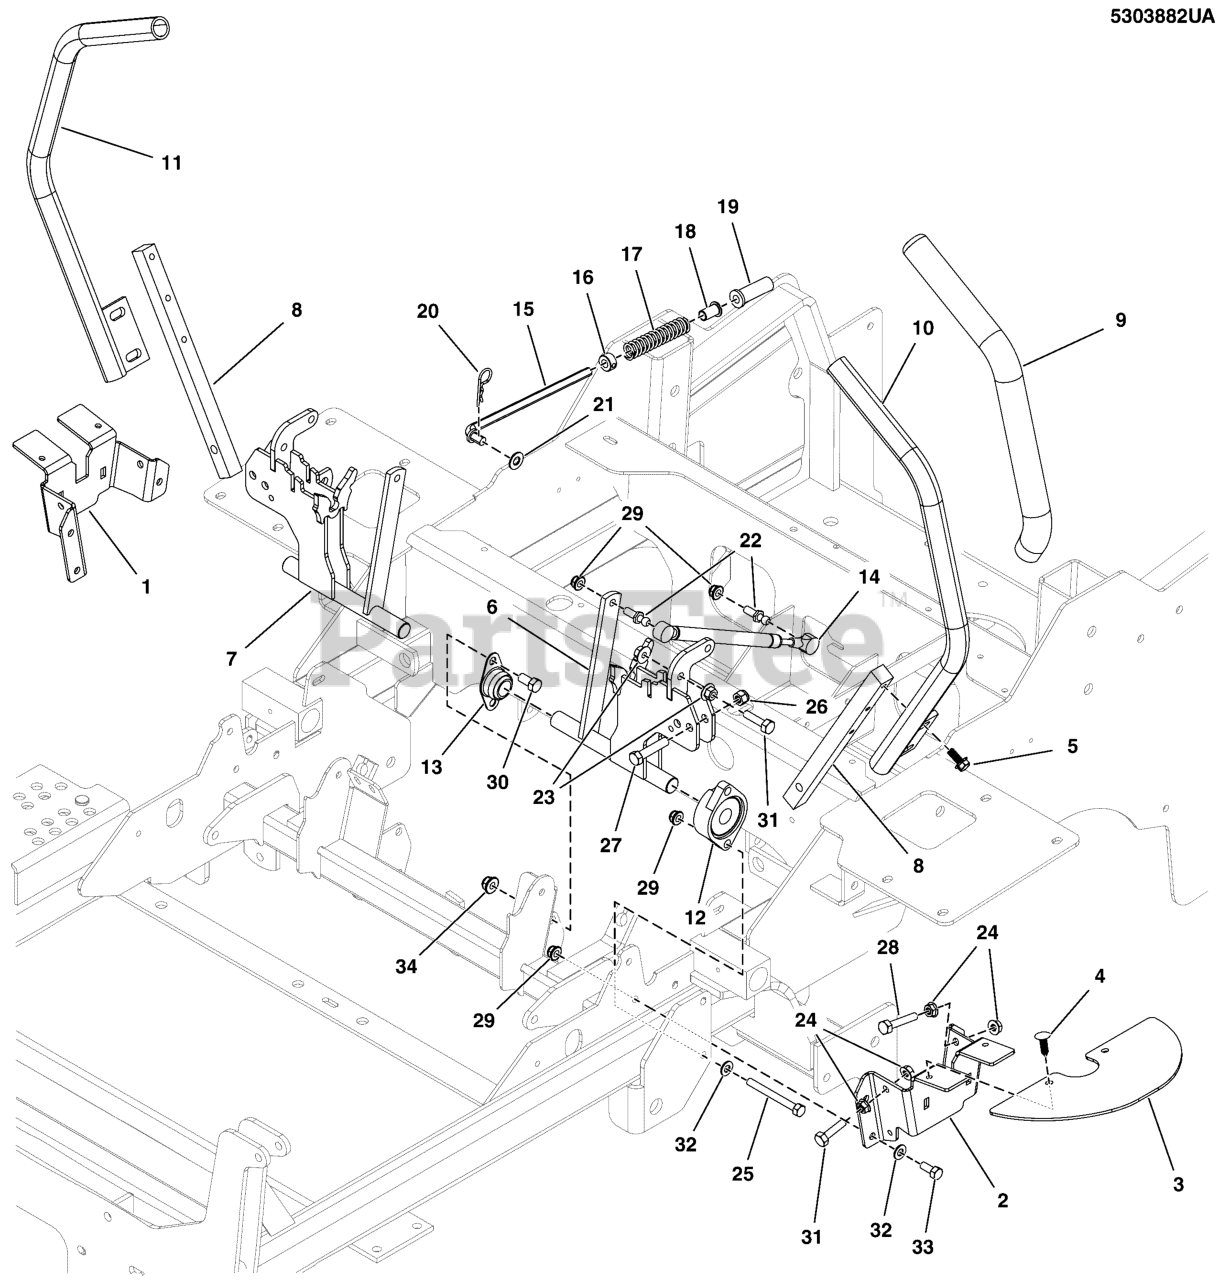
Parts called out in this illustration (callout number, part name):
1	PLATE, Neutral Lock, RH - BLK
2	PLATE, Neutral Lock, LH - BLK
3	GUARD, RUBBER MOTION CONTROLS
4	PUSH RIVET (TREE TYPE), BLACK
5	SCREW, 5/16-18x0.750, GR5, WHIZ-LOCK, ZC
6	WELD, CONTROL SHAFT, LOCKOUT, LH - BLK
7	WELD, CONTROL SHAFT, LOCKOUT, RH - BLK
8	MOUNT, CONTROL ARM - BLK
9	GRIP, FOAM, 1" ID, 16" LONG
10	WELD, HANDLE MOTION CNTRL, 16.5, 1.0, LH - BLK
11	WELD, HANDLE MOTION CNTRL, 16.5, 1.0, RH - BLK
12	BEARING, FLANGE
13	BEARING, BRONZE FLANGE, 3/4"
14	DAMPENER, CONTROL,#(P6709/P3610)
15	ROD, NEUTRAL RETURN, CZ
16	COLLAR, 3/8" Set
17	SPRING, REVERSE RETURN
18	BUSHING, FLANGE 3/8ID X 7/8 LONG
19	FLANGED BUSHING, 3/8IDX.63ODX.8125FL
20	3/32 X 1-5/8 HAIR PIN CLIP
21	WASHER, 3/8 SAE
22	10MM BALL STUD, 5/16-18 X 3/4 THDS
23	NUT, 5/16-18 HEX SERRATED FLANGE (LARGE)
24	NUT, 5/16-18 HEX SERRATED FLANGE (SMALL)
25	BOLT, 5/16-18 X 3" GD5 YZ
26	NUT, 3/8-16 HEX NYLON LOCK
27	BOLT, 3/8-16 X 1-3/4" GD5 CZ
28	BOLT, 5/16-18 X 1-3/4 TFL, GD5 YZ
29	NUT, 5/16-18 HEX NYLOCK FLANGE NUT
30	BOLT, 3/8-16 X 3/4" GD5 CZ
31	BOLT, 5/16-18 X 1-1/4 GD5 TFL, CZ
32	WASHER, 5/16" SAE
33	BOLT, 5/16-18 X 3/4 GD5
34	NUT, 3/8 - 16 HEX NYLOCK FLANGE
